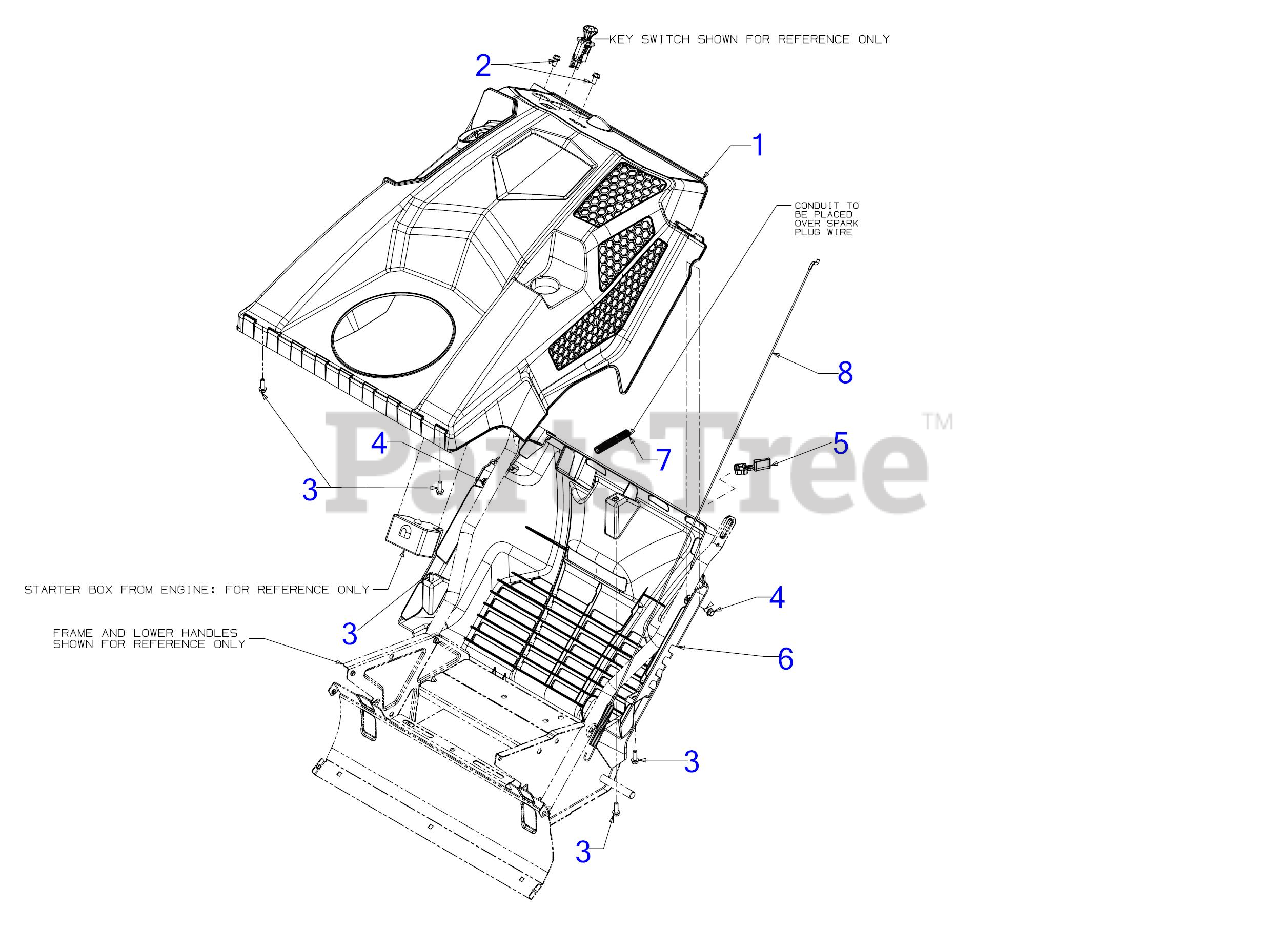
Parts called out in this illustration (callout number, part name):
1	21" COVER ASSEMBLY
2	HEX SCREW 1/4-15 x .50
3	SCREW 1/4-15 x .750
4	SCREW 1/4-20X.625
5	CHOKE EXTENION LEVER
6	BOTTOM COVER
7	CONVOLUTED CONDUIT
8	AUGER CLUTCH CABLE 37.05"
